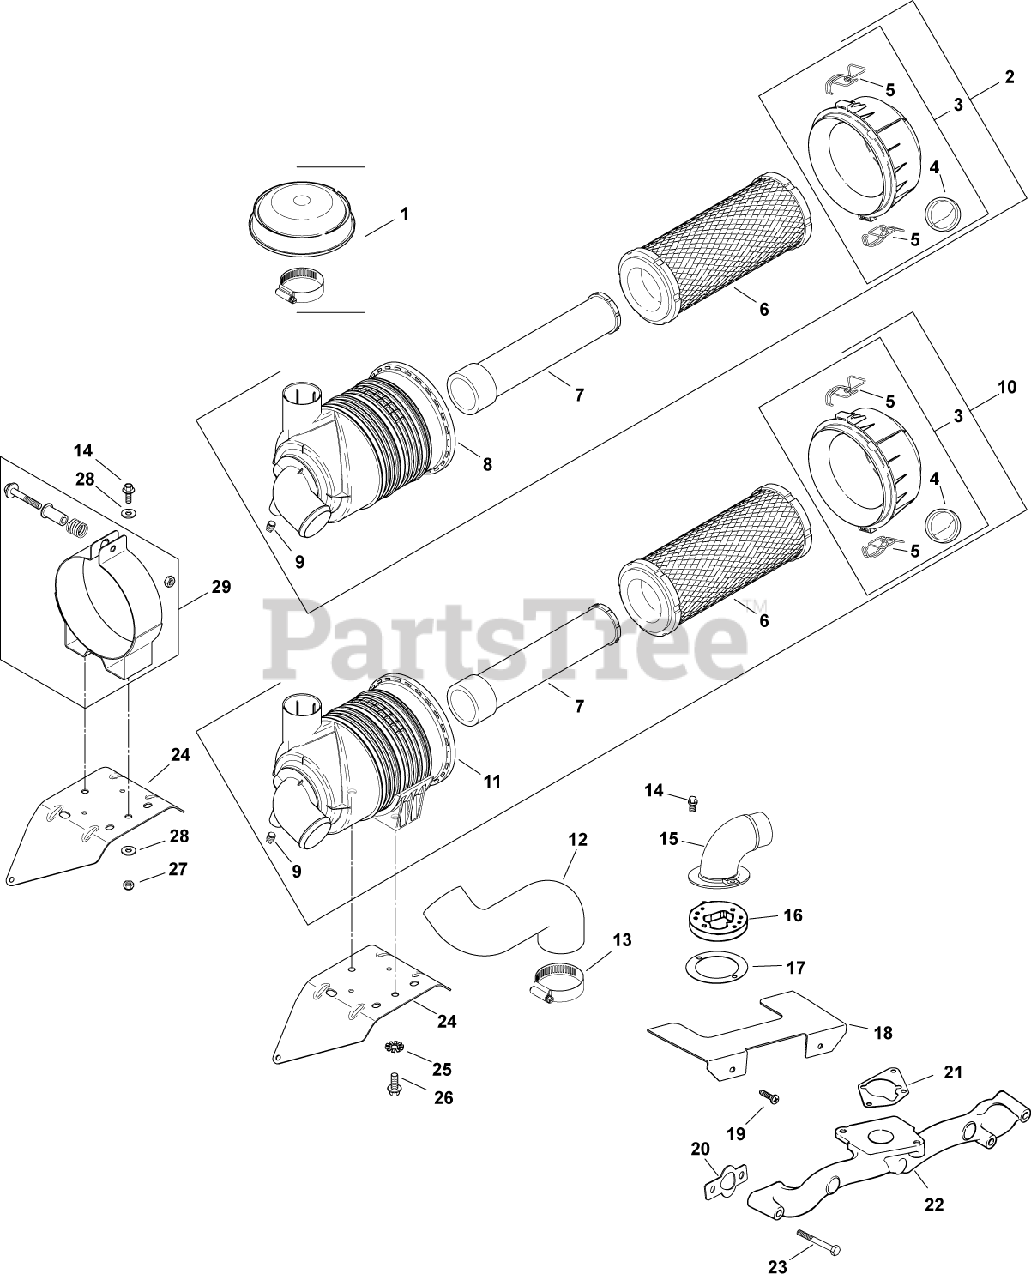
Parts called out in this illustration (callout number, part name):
1	HOOD, AIR CLEANER (5.25)-USE 25 324 04-S
2	AIR CLNR, CANISTER-USE 25 048 17-S
3	COVER ASSEMBLY, AIR CLEANER
4	VALVE, DUST EJECTOR
5	CLIP - USE 62 154 07-S
6	ELEMENT, AIR FILTER - PRIMARY
7	ELEMENT, AIR FILTER - SAFETY
8	HOUSING, HD AIR CLEANER
9	PLUG, PIPE
10	AIR CLEANER, CANISTER
11	HOUSING, HEAVY DUTY A/C
12	HOSE, AIR CLEANER
13	CLAMP, HOSE
14	SCREW, FLG M6X1.0X16
15	ADAPTER, REMOTE AIR CLEANER
16	ADAPTER ASSEMBLY (CH730)-USE 24 029 96-S
17	GASKET, ADAPTER
18	SHIELD, DEBRIS
19	SCREW, PHL HD 11-16X3/4"
20	GASKET, INTAKE MANIFOLD USE 24 041 79-S
21	GASKET, AIR CLEANER BASE
22	MANIFOLD, METAL INTAKE
23	SCREW, FLG M6X1.0X55
24	BRACKET, AIR CLEANER
25	WASHER,INT EXT TOOTH LOCK 5/16"
26	SCREW, FLG M8X1.25X20
27	NUT, LOCK M6X1.0
28	WASHER, FLAT 1/4" (O.D. 1")
29	BRACKET, AIR CLEANER-USE 24 126 191-S
M-639016-S	SCREW, FLG M6X1.0X16
